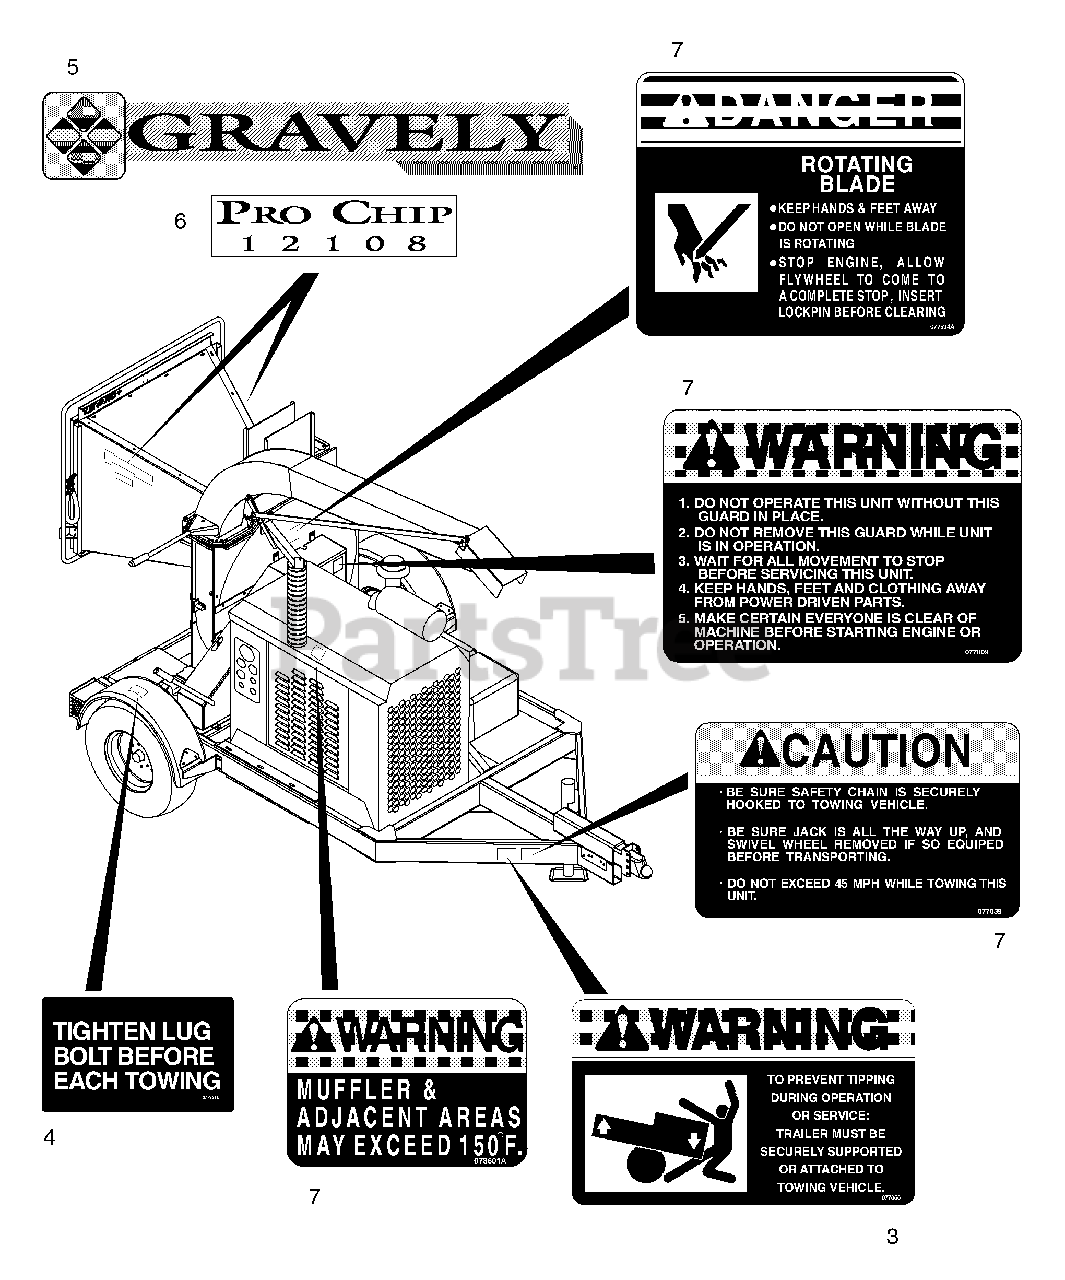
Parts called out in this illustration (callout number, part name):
3	Decal-WARNING-Tipping
4	Decal Set-Chipper Black/White
5	Decal-Gravely Name/Logo Set
6	Decal-Model Designation 12108 - set of 2
6	Decal-Model Designation 1299 - set of 2
6	Decal-Model Designation 1281 - set of 2
6	Decal-Model Designation 1286 - set of 2
6	Decal-Model Designation 12110 - set of 2
6	Decal-Model Designation 12115 - set of 2
7	Decal Set-Large Chippers
